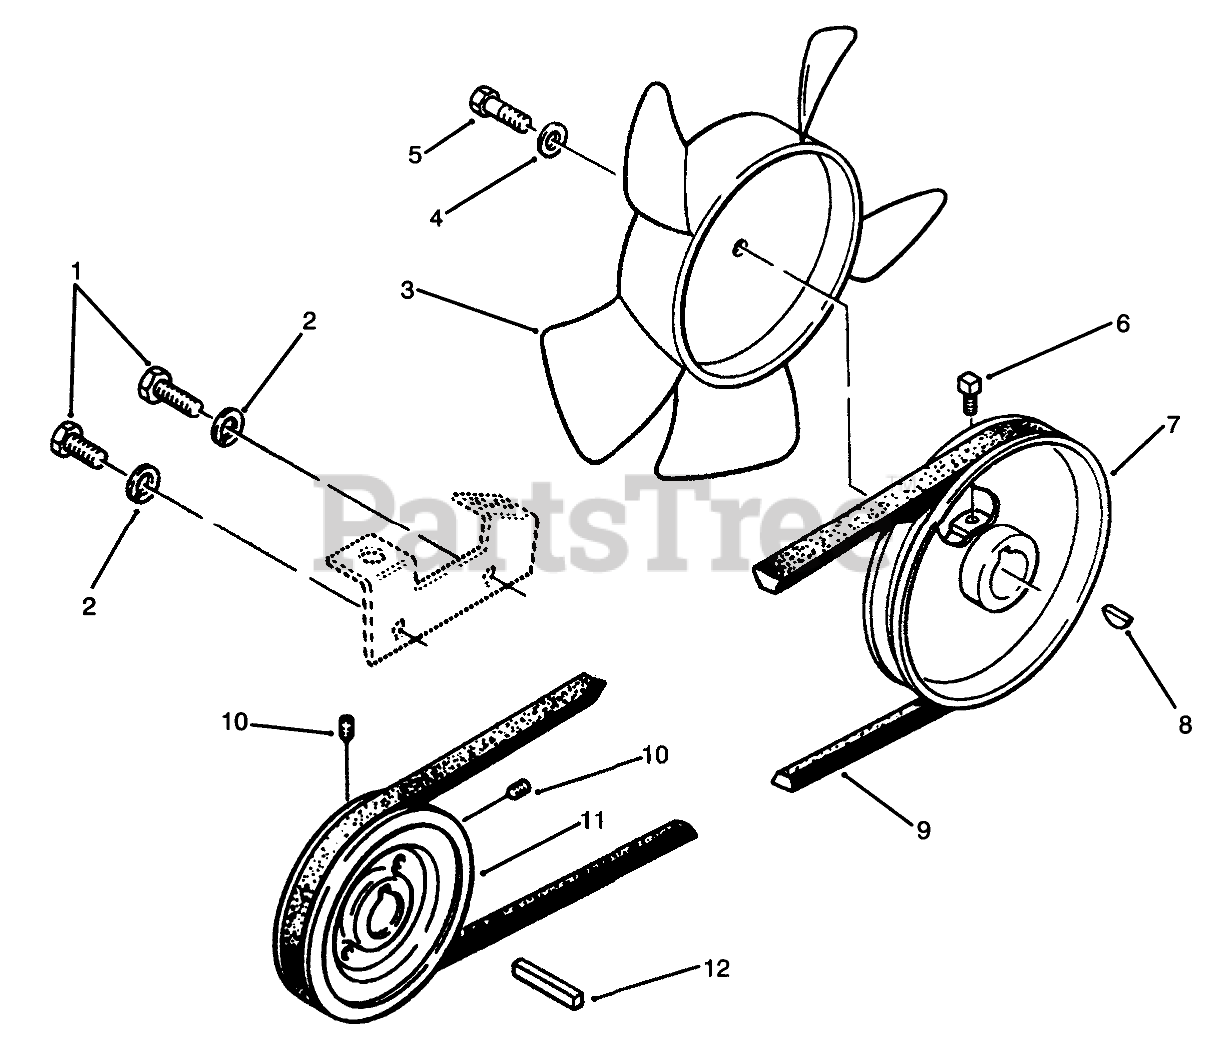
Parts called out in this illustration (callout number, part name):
1	SCREW-HH
2	WASHER-FLAT
3	NYLON FAN-L-CW
4	WASHER
5	SCREW-HEX HD CAP
6	SCREW-SQH
7	PULLEY
8	KEY-WOODRUFF
9	BELT-V
10	SCREW-SET, HSH
11	PULLEY
